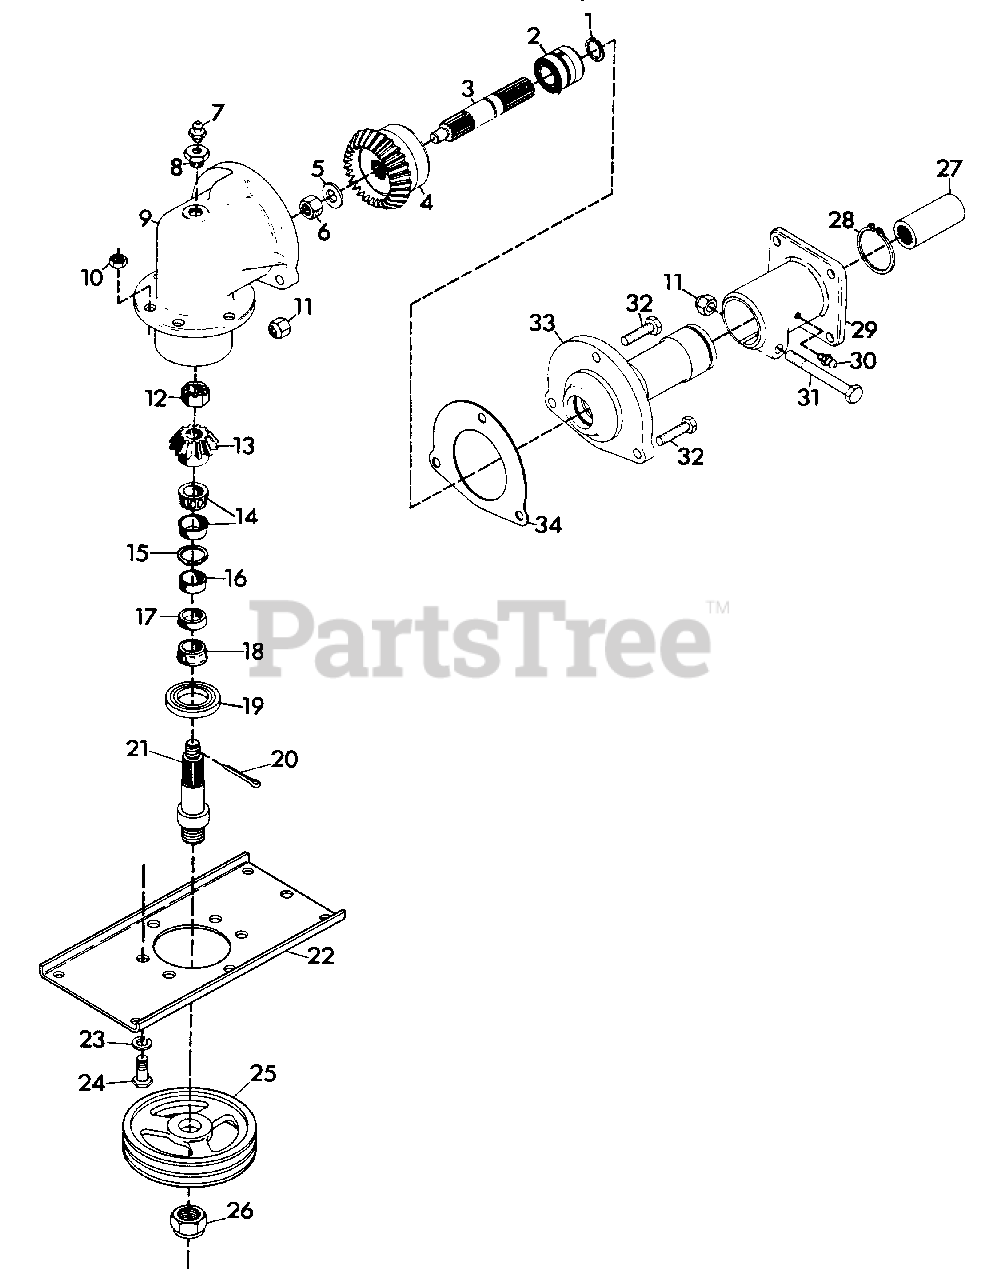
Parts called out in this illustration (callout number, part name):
1	RING, RETAINING .937 SHAFT
2	ASSEMBLY, BEARING 1.000X1.980X1.243
3	SHAFT, DRIVE
4	GEAR, BEVEL
5	WASHER, FLAT .687X1.312X.122
6	NUT, LOCK 5/8-18
7	FITTING, LUBE 1/8 NPT
8	BUSHING, 1/2 REDUCING PIPE
9	HOUSING, GEAR
10	NUT, JAM 1/2-13
11	NUT, LOCK 1/2-13
12	NUT, SLOTTED 5/8-18
13	PINION, BEVEL
14	ASSEMBLY, BEARING CUP AND CONE
15	RING, RETAINING 2.000 BORE
16	SPACER
17	CUP, BEARING
18	CONE, BEARING
19	SEAL, OIL(DUAL LIP)
20	PIN, COTTER .094X1.25
21	SHAFT, ROTOR
22	PLATE, MOUNTING
23	WASHER, LOCK 1/2 REG.
24	BOLT, HEX SPECIAL
25	SHEAVE, 1/2X6 DOUBLE GROOVE
26	NUT, SPECIAL 1-14
27	COUPLING
28	RING, RETAINING EXTERNAL 2.25 SHAFT
29	CASTING, SWIVEL
30	FITTING, LUBE 1/4-28
31	BOLT, HEX 1/2-13X3.25
32	BOLT, HEX 1/2-13X1.75
33	HOUSING, SHAFT
34	SHIM, .005
